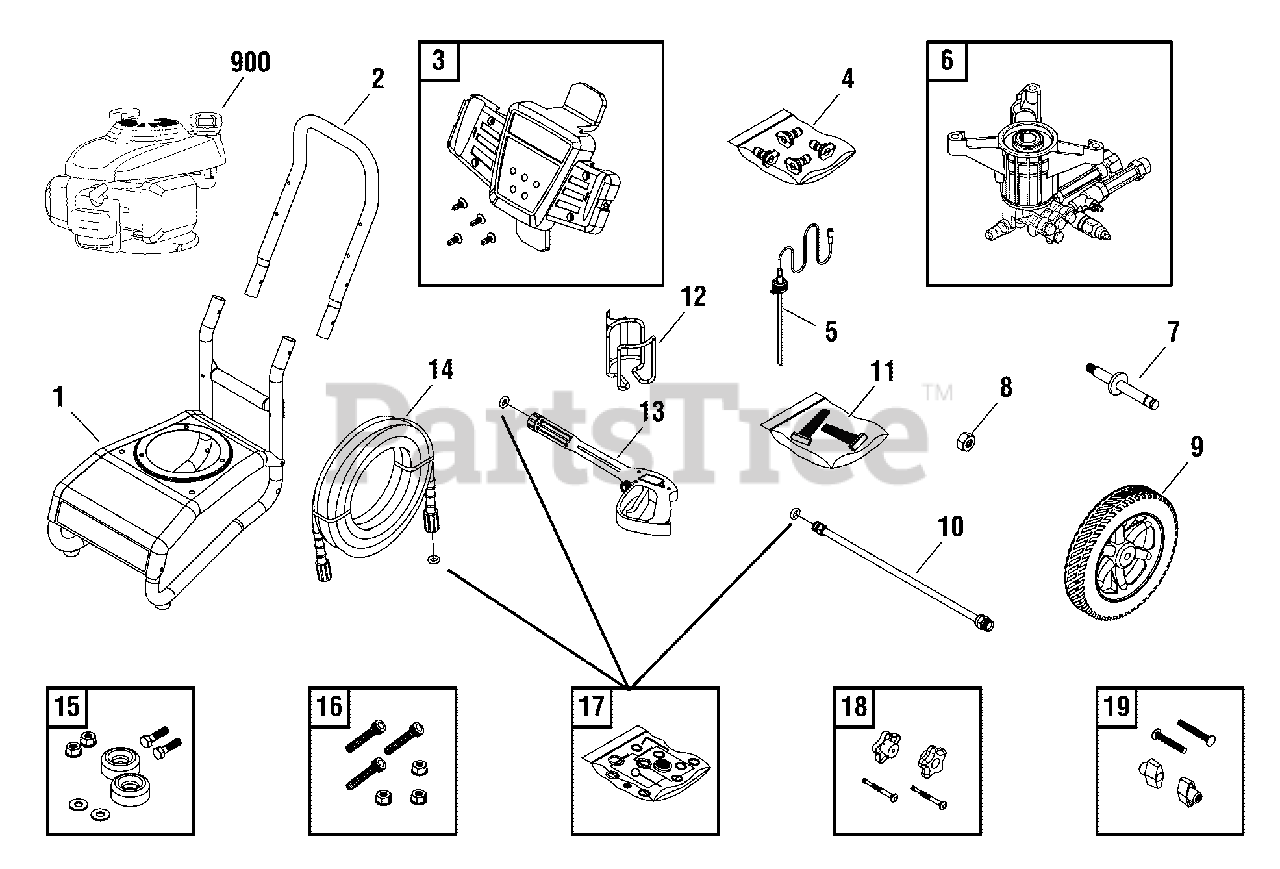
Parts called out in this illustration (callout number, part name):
1	BASE
10	EXTENSION, QC
13	GUN
14	HOSE
15	MOUNT, Vibration
16	KIT, Hardware, Pump Mounting
900	* ENGINE
